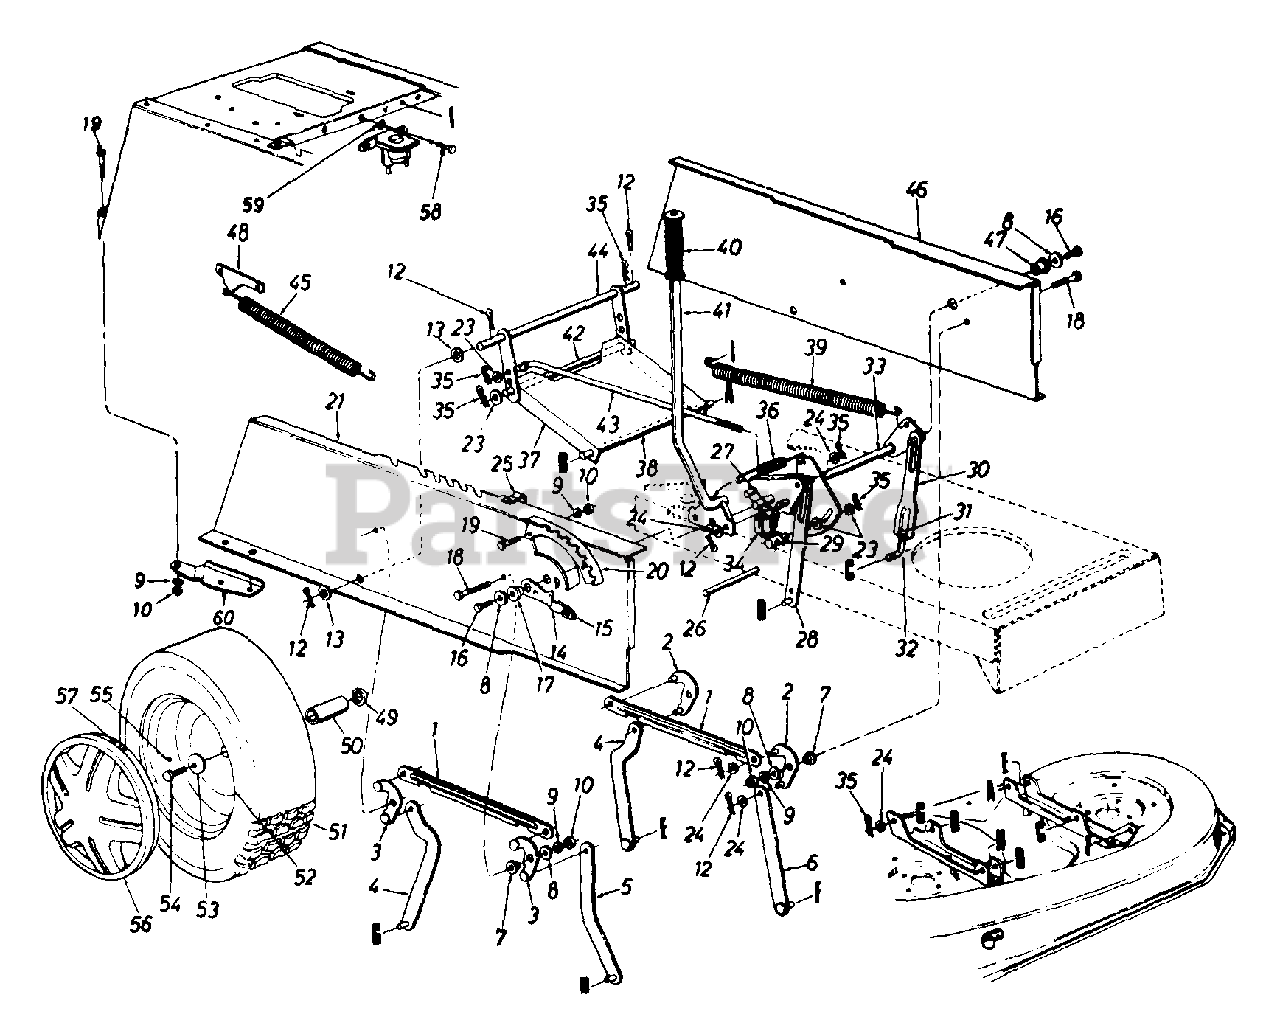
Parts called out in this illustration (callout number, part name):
1	Connecting Rod
2	Pivot Link Ass'y.- L.H.
3	Pivot Link Ass'y.- R.H.
7	Shld. Spacer .318" I.D.
8	Fl-Wash..344" I.D. x .62" O.D.
9	L-Wash. 5/16" I.D.
10	Hex Nut 5/16-18 Thd.
12	Cotter Pin 1/8" Dia.
13	Fl-Wash..635" I.D. x 1.0" O.D.
14	Deck Lift Stop
15	Knobs
16	Hex TT-Tap Scr. 5/16-18 x .75"
17	Flange Brg..63" I.D.
18	Hex Wash. Hd. Scr. 5/16-18 x .875"
19	Hex Bolt 5/16-18 x .75" Lg.
20	Index Brkt.
21	Upper Frame - R.H.
23	Fl-Wash..385" I.D. x .87" O.D.
24	Fl-Wash..531" I.D. x .93" O.D.
25	Clamp
26	Running Board Rod
27	Hex Tap Scr. #12 x .375"
31	Hex Nut 1/2-20 Thd. (Gr. 5)
32	Lift Link Adjuster
35	Inter. Cotter Pin 3/8" Dia.
36	Extension Spring
37	Stabilizer Bracket
38	Shaft 1/2" Dia. x 10.28" Lg.
39	Extension Spring
40	Grip (Lift Handle)
41	Deck Lift Handle Ass'y.
42	Shaft 9.34" Lg.
43	Disengagement Rod
44	Stabilizer Shaft Ass'y.
45	Extension Spring
46	Upper Frame - L.H.
47	Flange Brg..632" I.D.
48	Deck Spring Brkt.
49	Fl-Wash..76" I.D. x 1.49" O.D.
50	Sleeve .75" I.D. x 1.0" O.D.
52	Wheel Rim Only
53	Bell-Wash..345" I.D. x .88"
54	Hex L-Bolt 5/16-24 x .75" Lg.
55	Air Valve
56	Hub Cap (Beige)
57	Spring Clip
58	Hex Wash. Hd. TT-Tap Scr. 1/4-20 Thd.
59	Ext. L-Wash. 1/4" I.D.
